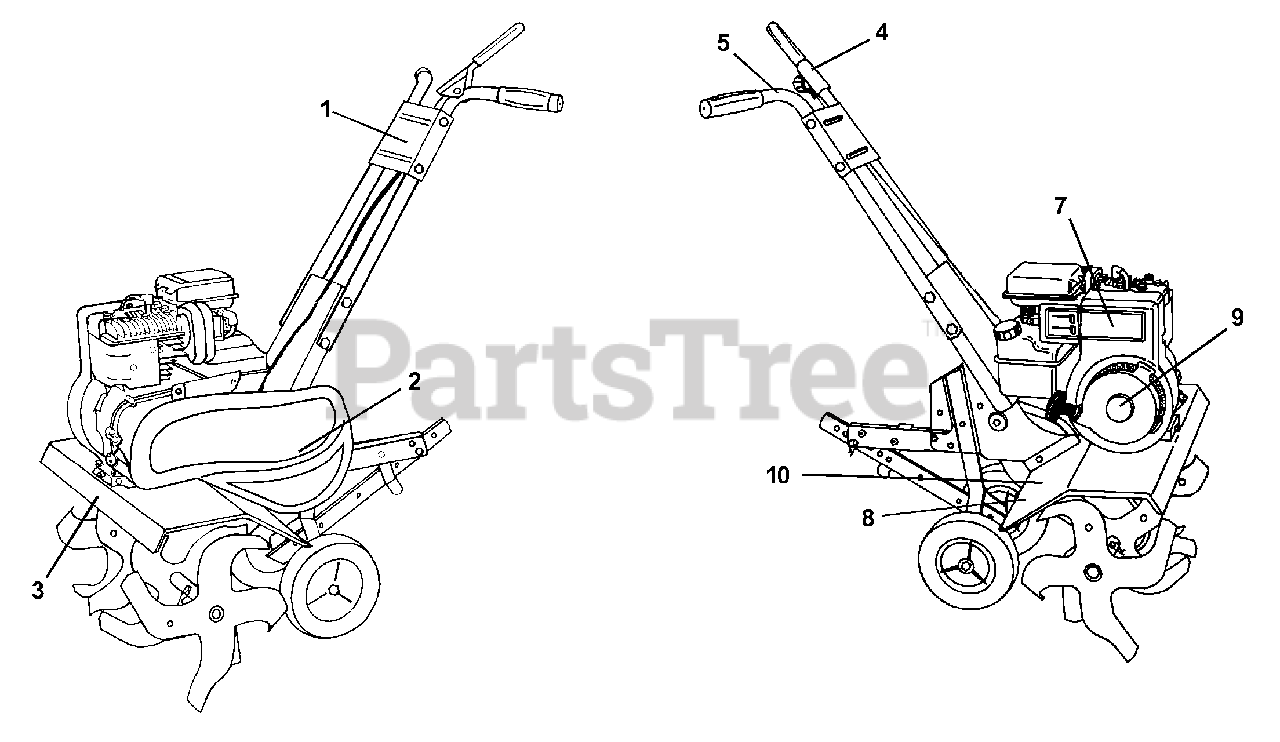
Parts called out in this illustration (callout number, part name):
1	Decal, Logo
2	Decal, Logo
3	Decal, Description
4	Decal, Tine Control
5	Decal, Hand Placement
7	Decal, Briggs & Stratton
8	Decal, Warning, Rotating Tines
9	Decal, 5 HP
10	Decal, Warning
